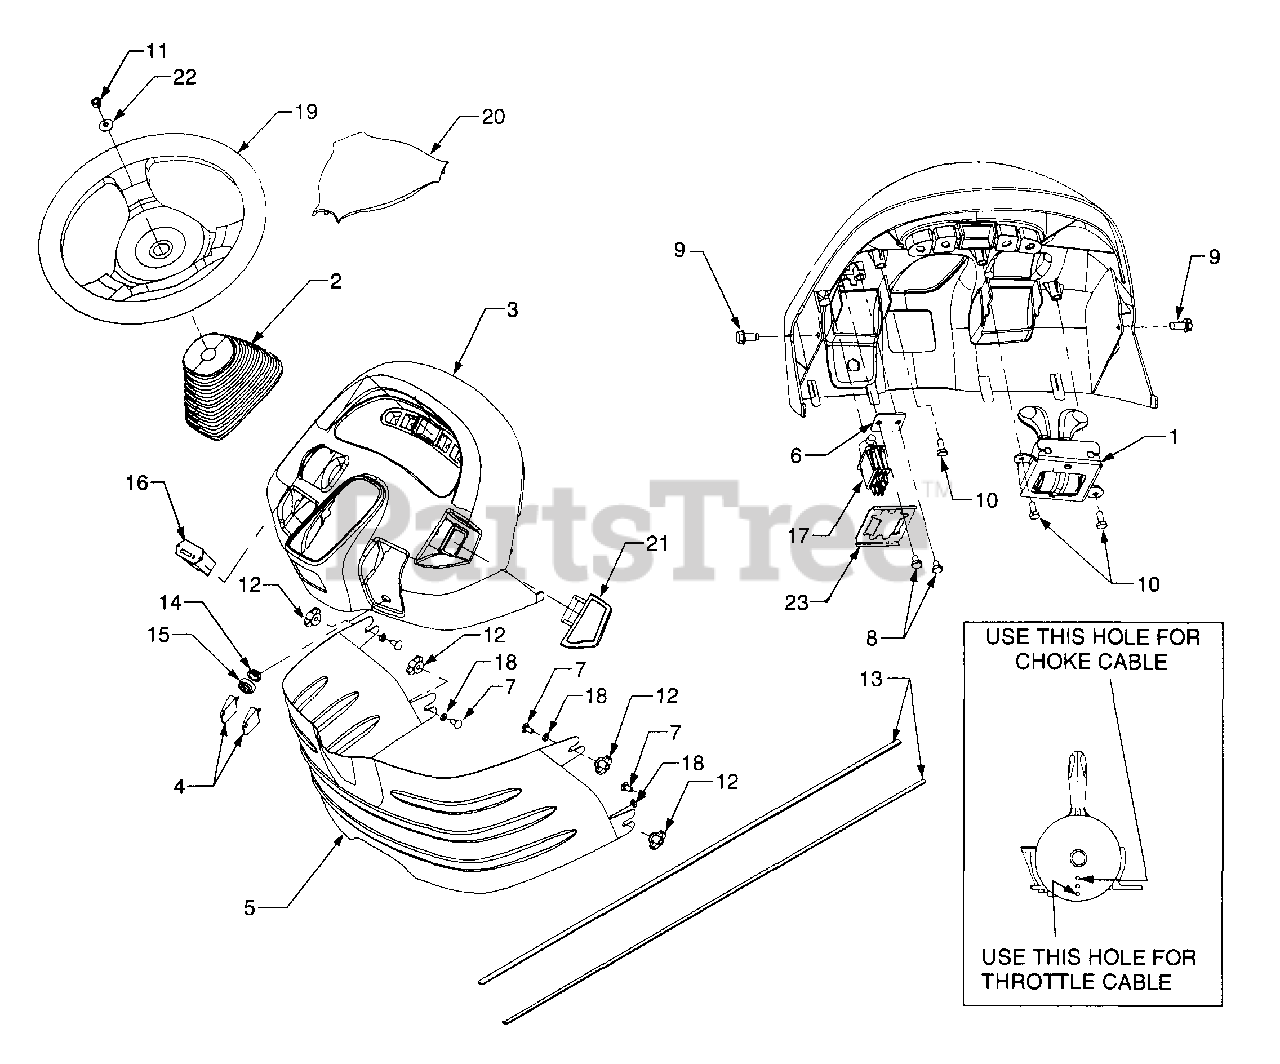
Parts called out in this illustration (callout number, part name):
1	Control Assembly, Throttle/Choke
2	Boot, Tilt Steer
3	Dash Panel
4	Key, Ignition (Set of 2)
7	Carriage Bolt, 1/4-20 x .62
8	Screw, Hex Cap 1/4-20 x .375 GR5
9	Screw, Hex Wash. Hd. Tapp 5/16-18 x .75
10	Screw, Hex Cap 1/4-20 x .50 GR5
11	Nut, Hex Lock, 5/16-24
12	Wing Nut, 1/4-20 w/Bell Washer
13	Seal, Screen
14	Nut, Ignition Switch, 5/8-32
15	Cap, Ignition Switch
16	Hour Meter
17	Switch, PTO
18	Nut, Push
19	Steering Wheel
20	Cover, Steering Wheel
21	Handle, PTO Switch
22	Washer, Belleville, .34 x .872
23	Bracket, PTO Switch Retainer
